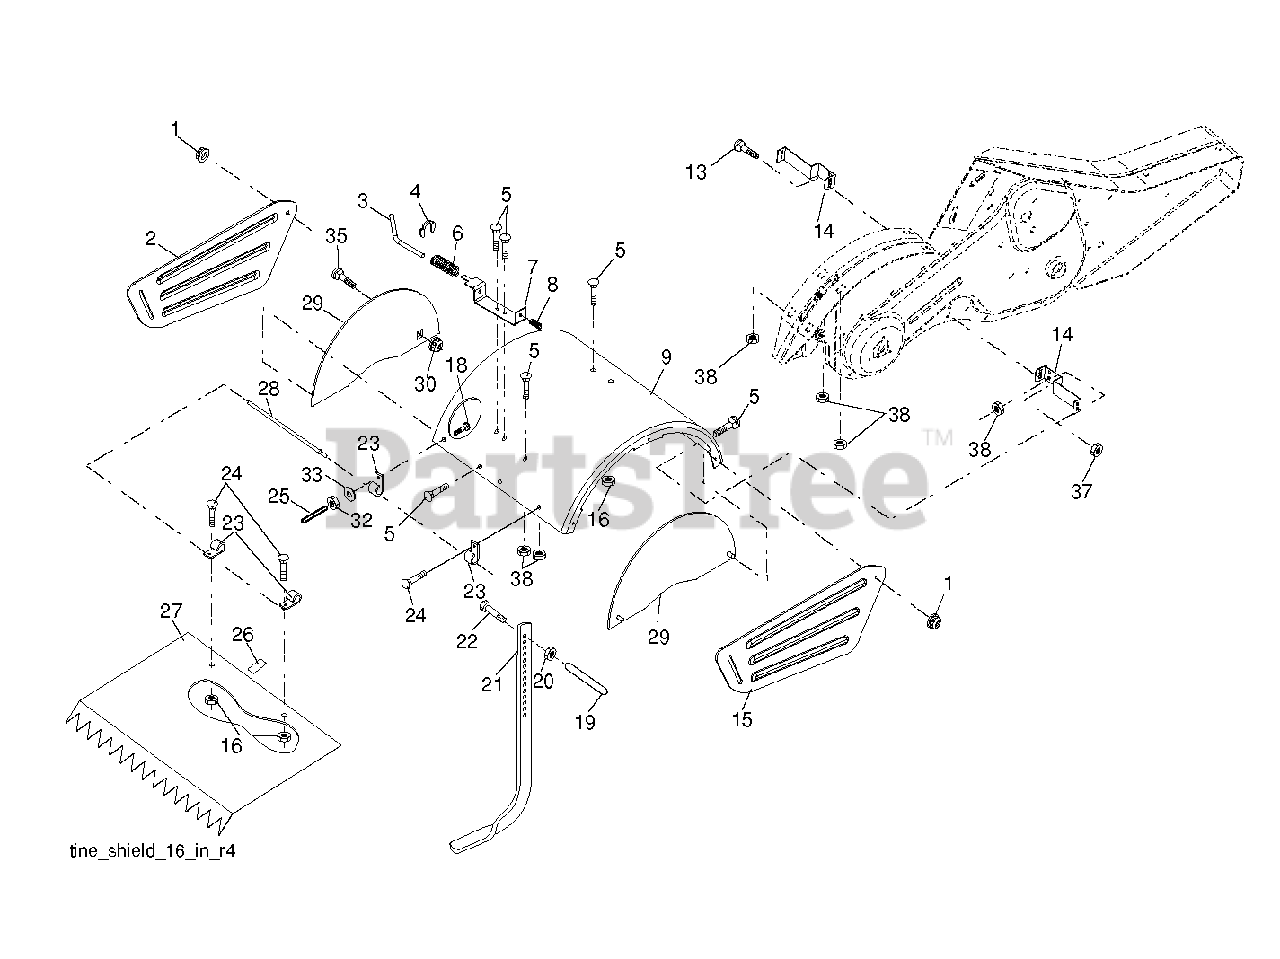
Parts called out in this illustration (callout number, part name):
1	NUT LOCK HEX FLANGE 5/16-18
3	STAKE PIN TI
4	RING, KLIP
5	BOLT, RDHD SQNK 5/16-18 X 3/4
6	SPRING TI
7	LATCH BRACKET TI
8	SPRING CRT
13	BOLT.CARRIAGE.5/16-18
14	BRACKET.TINE.SHIELD.TILLER
16	NUT T
20	NUT.HEX.3/8-16UNC
21	STAKE DEPTH CRT
22	BOLT.375-16
23	HINGE CRT
24	BOLT
25	VINYL CAP TI
26	PAD IDLER TI
28	PIN.HINGE.TILLER
30	LOCKNUT-FLANGE 5/16-18
32	NUT
33	LOCKWASHER
35	BOLT
37	NUT.71038.31-18.HEX.NYLOCK
38	NUT
